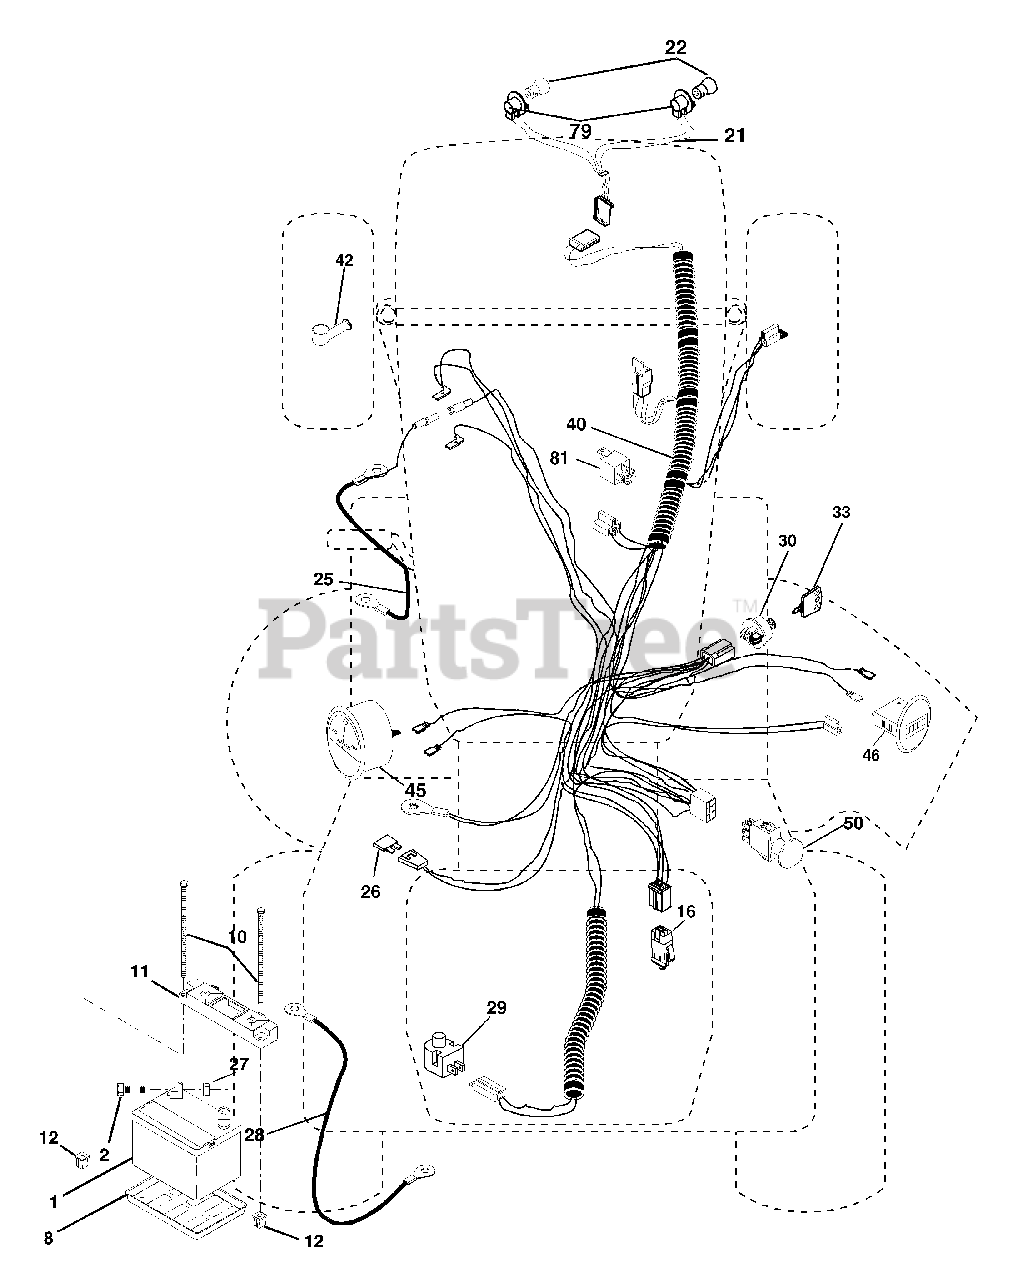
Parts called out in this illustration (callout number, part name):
1	Battery
2	Bolt Hex Head 1/4-20 x 3/4
8	Tray, Battery
10	Bolt, Battery Front 1/4-20 x 7.5 Zinc
11	Holddown Battery Front Mount
12	Nut, Push Nylon 1.4" Battery Front
16	Switch Interlock Push-In
21	Harness Socket Light w/4152J
22	Bulb Light
27	Nut Keps Hex 1/4-20
28	Cable Bolt Ground
29	Switch, Plunger NC Gray
30	Switch, Ign
40	Harness Ign.
42	Cover, Terminal Red
50	Switch, PTO
79	Bulbholder Asm
81	Relay Asm.
